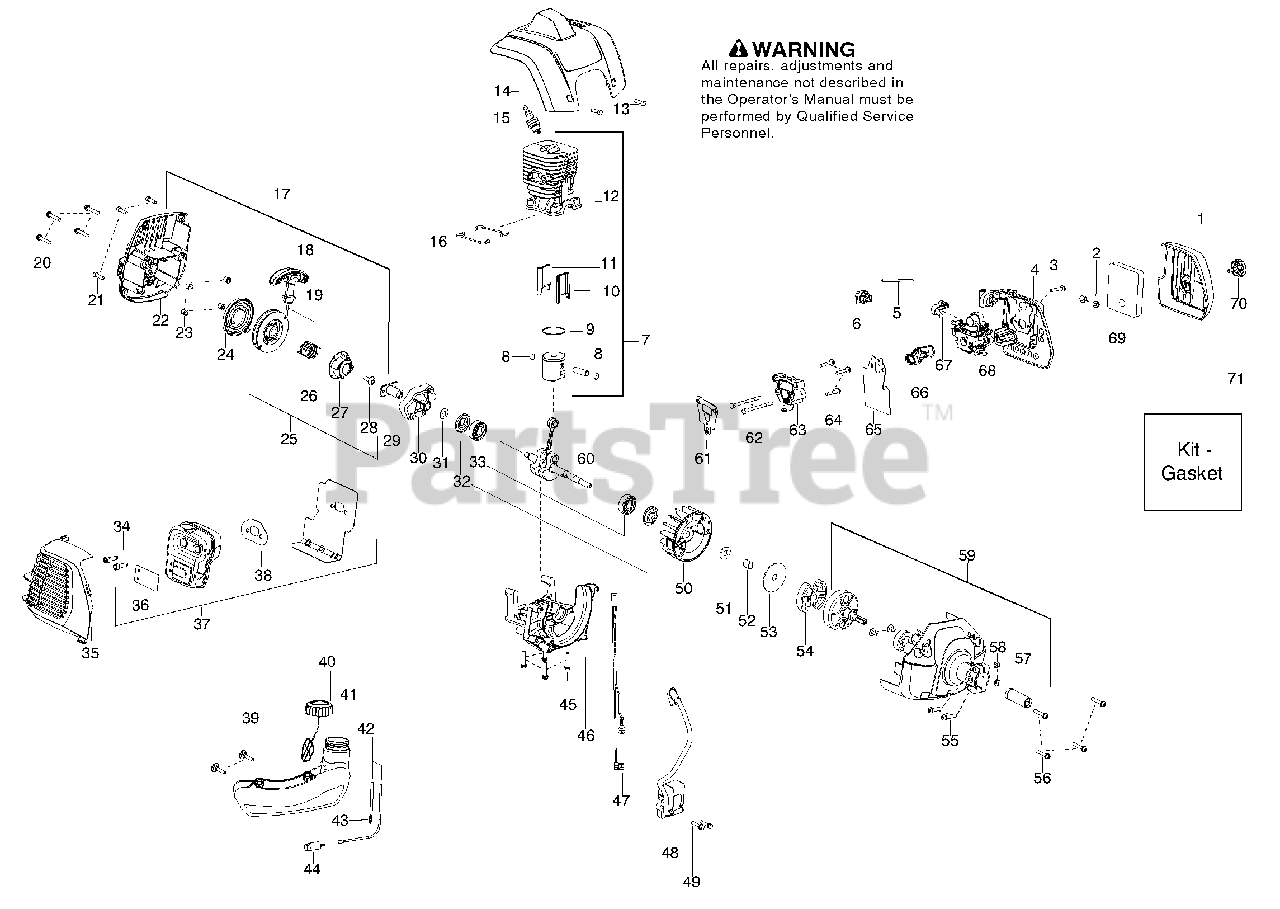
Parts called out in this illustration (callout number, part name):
1	Cover-Airbox
2	Nut-Carb. Screw
3	Screw 8-32
4	Base-Airbox
6	Purge Bulb
7	Kit-Piston/Cyl.
8	Retainer-Piston pin
9	Ring-Piston
10	Insert-Front Transfer Port
11	Insert-Rear Transfer Port
12	Cylinder-Machined
13	Screw M4 x1.75 x 16mm
14	Cover-Top
15	Spark Plug (RCJ- 6Y)
16	Seal-Cylinder(Kit)
17	Assy-Shroud Rear
18	Handle-Starter
19	Kit-Rope
20	Screw M4 x .8 x 25mm
21	Screw M4 x 1.75 x 16mm
22	Housing-Starter w/eyelet
24	Kit-Starter Spring
25	Kit-Pulley
26	Spring-Starter Hub
27	Hub-Starter
28	Screw M6
29	Coupling-Starter
30	Assy-Starter Cup
31	Washer-Flat
32	Seal-Crankshaft (kit)
33	Bearing-Crankshaft
34	Bolt-Muffler
35	Guard-Muffler
36	Kit-Spark Arrestor
37	Assy-Muffler
38	Gasket-Muffler (kit)
39	Screw-Tank Retainer
40	Assy-Fuel Cap w/ret.
41	Assy-Tank
42	Kit-Fuel line
43	Fitting-Fuel Line
44	Assy-Fuel Pickup
45	Screw-m5x25mm
46	Crankcase
47	Assy-Leadwire
48	Module-Ignition
49	Screw 8-32
50	Assy-Flywheel
52	Spacer-Flywheel
53	Washer-Clutch
54	Kit-Clutch Assy.
55	Screw 10-24 x 1"
56	Screw M5 x 25mm
57	Guide-Clutch Drum
58	Locknut 10-24
59	Assy-Fan Hsg
60	Kit-Crankshaft
61	Gasket - Adapter / Cyl.(kit)
62	Bolt M5 x .80
63	Adaptor-Carburetor
64	Screw .20 x 32
65	Gasket-Carb./Adapter(kit)
66	Boot-Carb.
67	Lever - Choke
68	Kit-Carburetor
69	Filter-Air
70	Assy-Airbox Knob
71	Kit - Gasket
